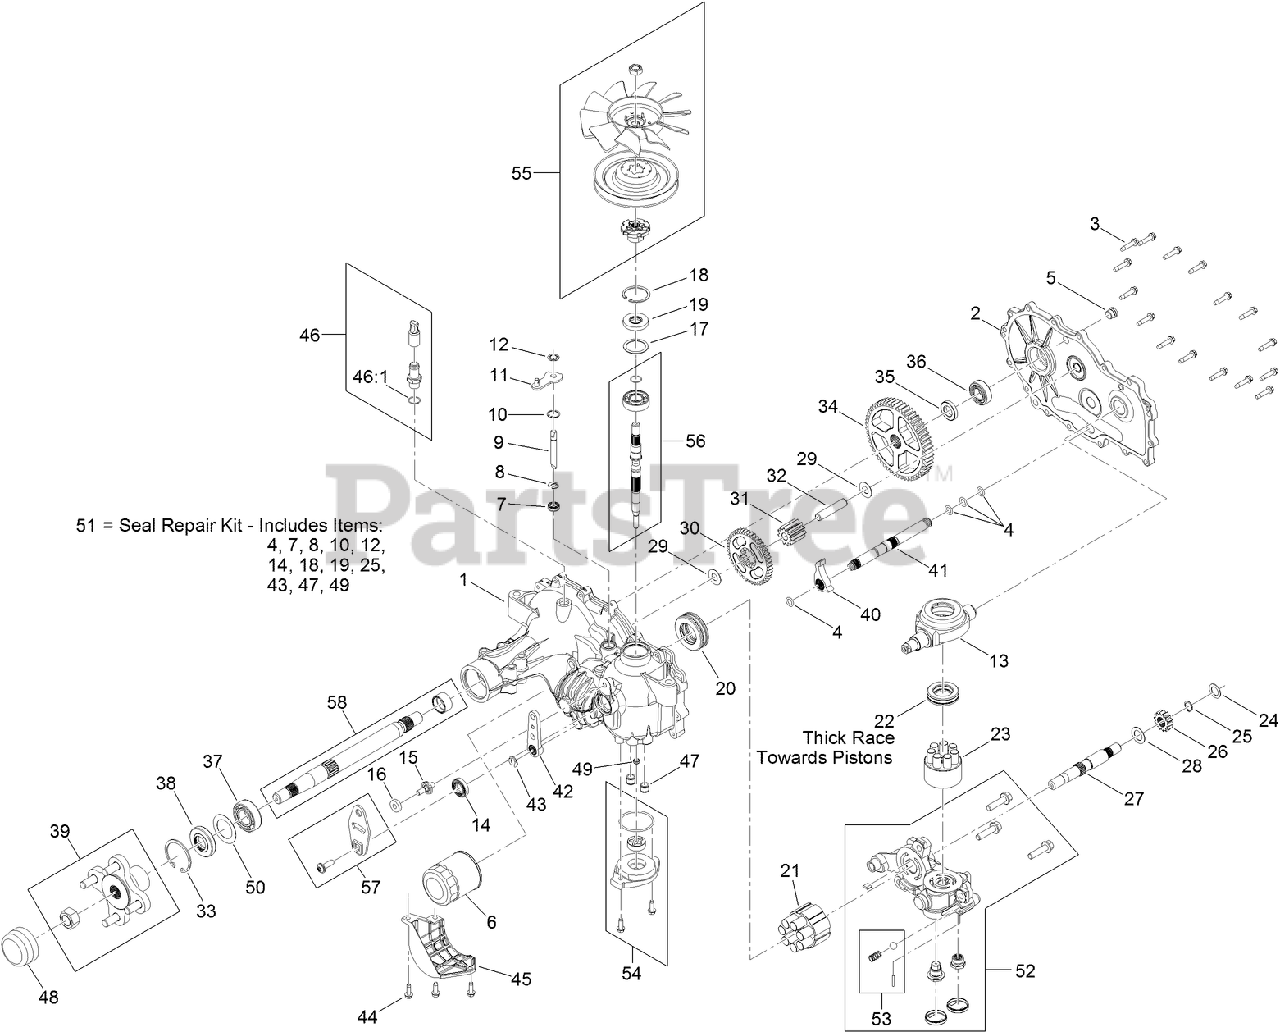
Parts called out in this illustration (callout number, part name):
1	MAIN HOUSING KIT
2	RH HOUSING SIDE KIT
3	SCREW-HHF
4	O-RING
5	PLUG-THREAD, STRAIGHT
6	ELEMENT-OIL FILTER, HYD
7	SEAL-LIP
8	RING-RETAINING, EXTERNAL
9	ROD-BYPASS
10	RING-RETAINING, INTERNAL
11	ARM-BYPASS
12	RING-RETAINING, EXTERNAL
13	SWASHPLATE-TRUNNION
14	SEAL-LIP
16	PUCK-FRICTION
17	SPACER
18	SEAL-LIP
19	RING-RETAINING
20	BEARING-THRUST
21	MOTOR CYLINDER BLOCK KIT
22	BEARING-THRUST
23	PUMP BLOCK ASM
24	WASHER-FLAT
25	RING-RETAINING
26	GEAR-14T
27	SHAFT-MOTOR
28	WASHER
29	WASHER
30	GEAR-45T
31	GEAR-11T
32	PIN-JACKSHAFT
33	RING-RETAINING
34	GEAR-54T
35	SPACER
36	BEARING-BALL
37	BEARING-BALL
39	HUB KIT
40	PAWL-BRAKE
41	SHAFT-BRAKE
42	HANDLE-BRAKE
43	RING-RETAINING, EXT
45	GUARD-FILTER, RH
46	ADAPTER-STRAIGHT
46:1	O-RING
47	TUBE-CONNECTING
48	COVER-NUT, AXLE
49	SEAL-GEROTOR
50	SPACER
51	SEAL KIT
52	RH CENTER SECTION CHARGE KIT
53	CHARGE RELIEF KIT
54	CHARGE KIT
55	FAN AND PULLEY KIT
56	INPUT SHAFT KIT
57	CONTROL ARM KIT
58	AXLE SHAFT KIT
